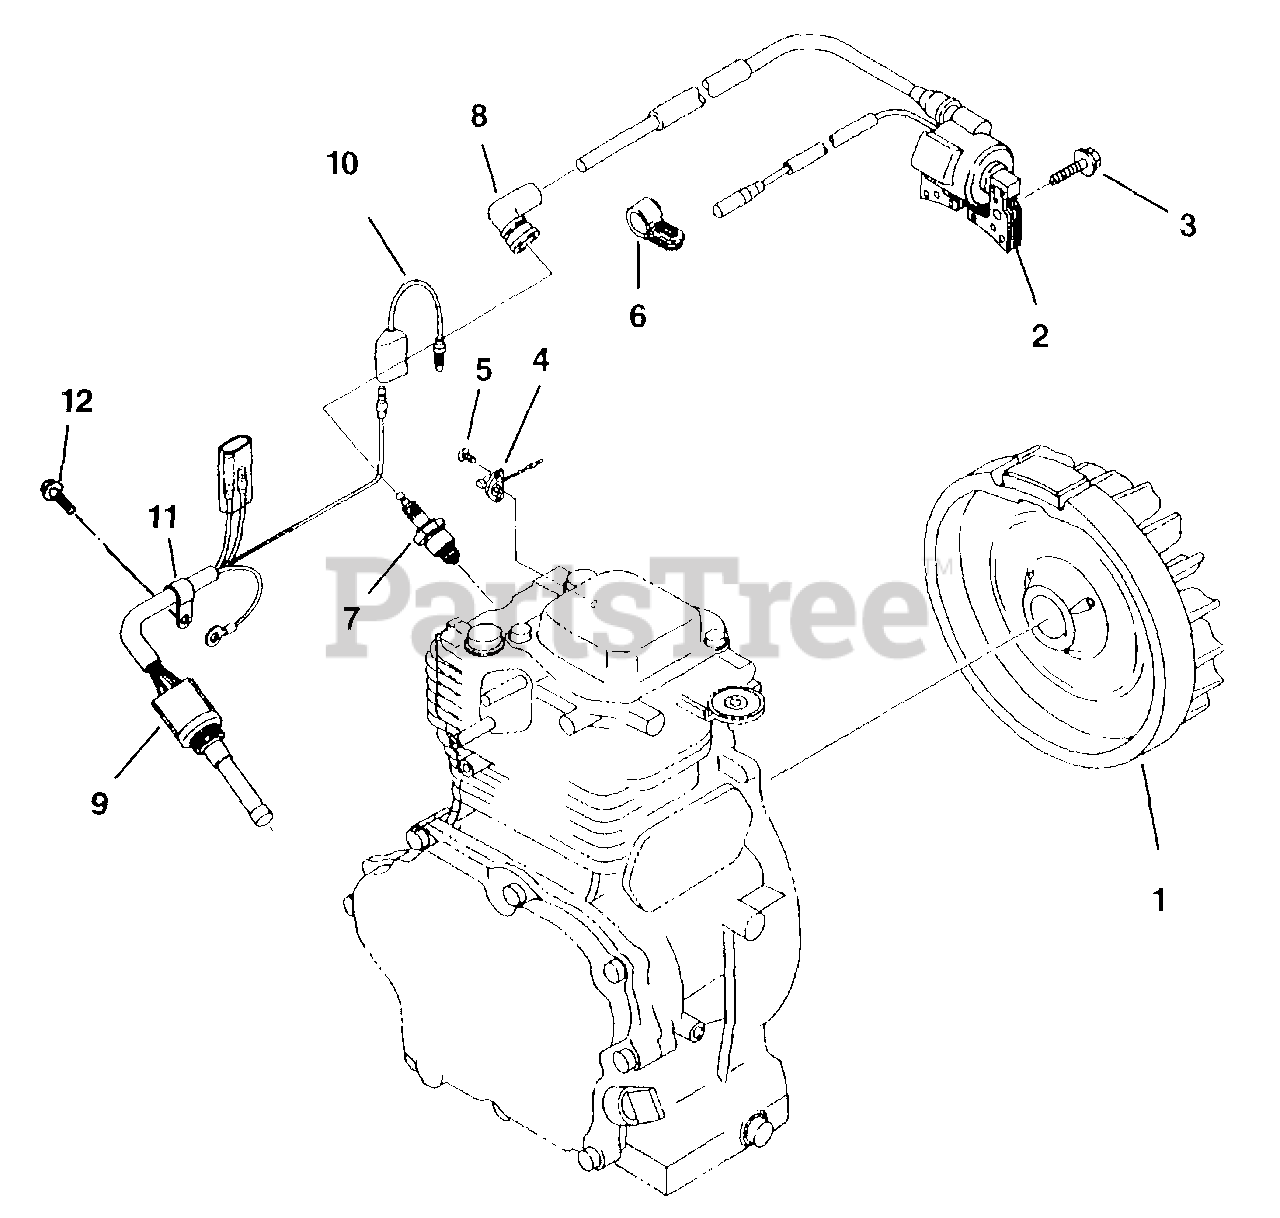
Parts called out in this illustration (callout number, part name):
1	Flywheel
2	Ignition coil
3	Bolt & washer
4	Switch ay
5	Tapping screw
7	Spark plug
8	Spark plug cap
9	Oil sensor
12	Bolt & washer
